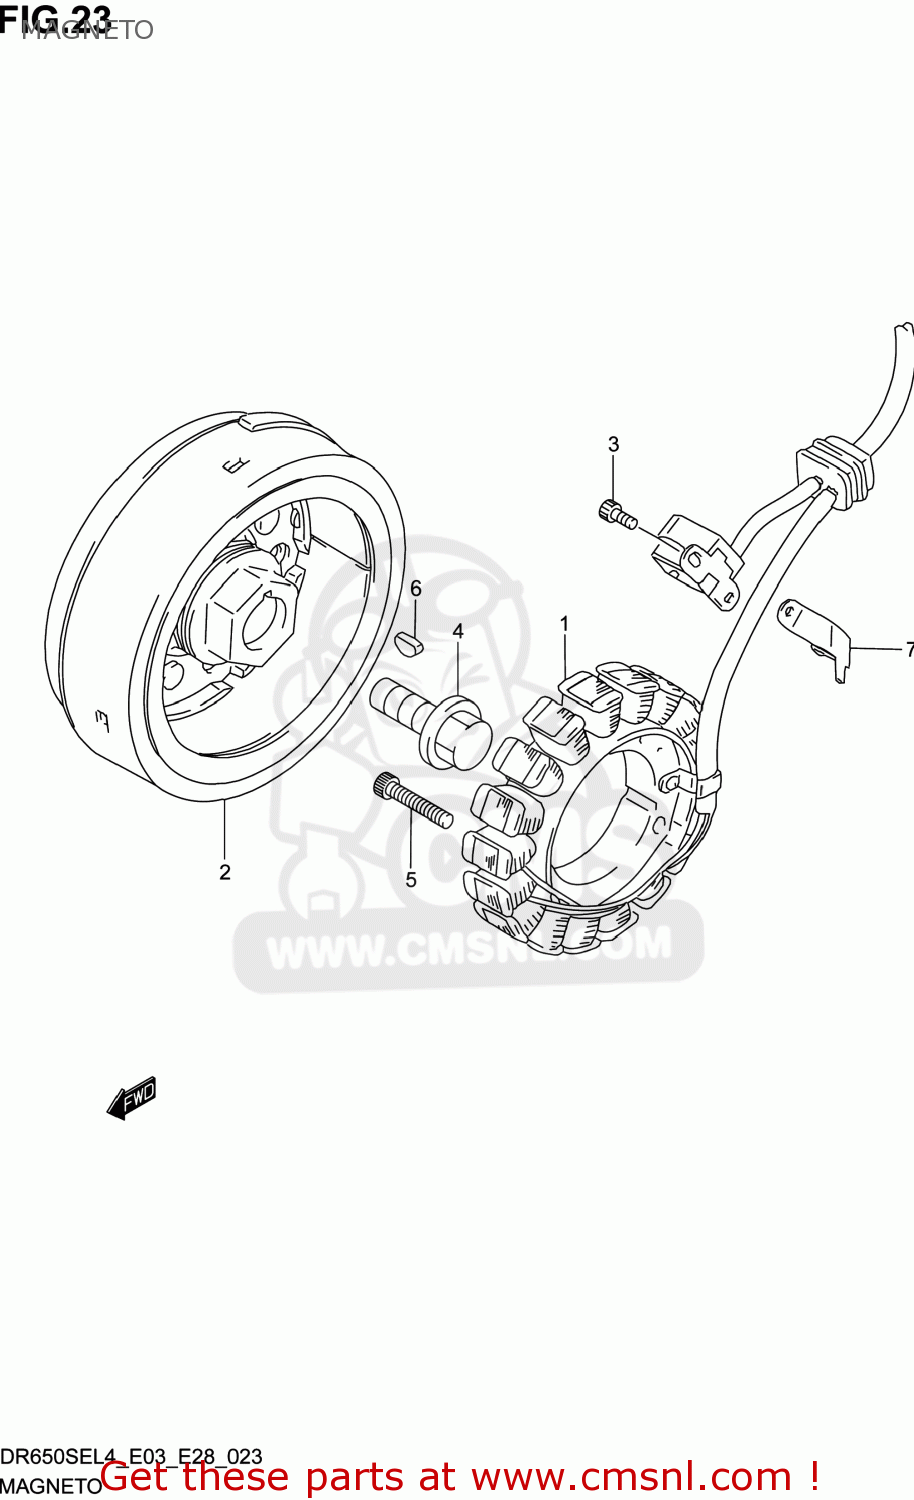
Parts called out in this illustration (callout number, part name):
1	STARTER ASSY
2	ROTOR ASSY
3	BOLT
4	BOLT(14X43)
5	BOLT
6	KEY
7	CLAMP,MAGNETO LEAD
